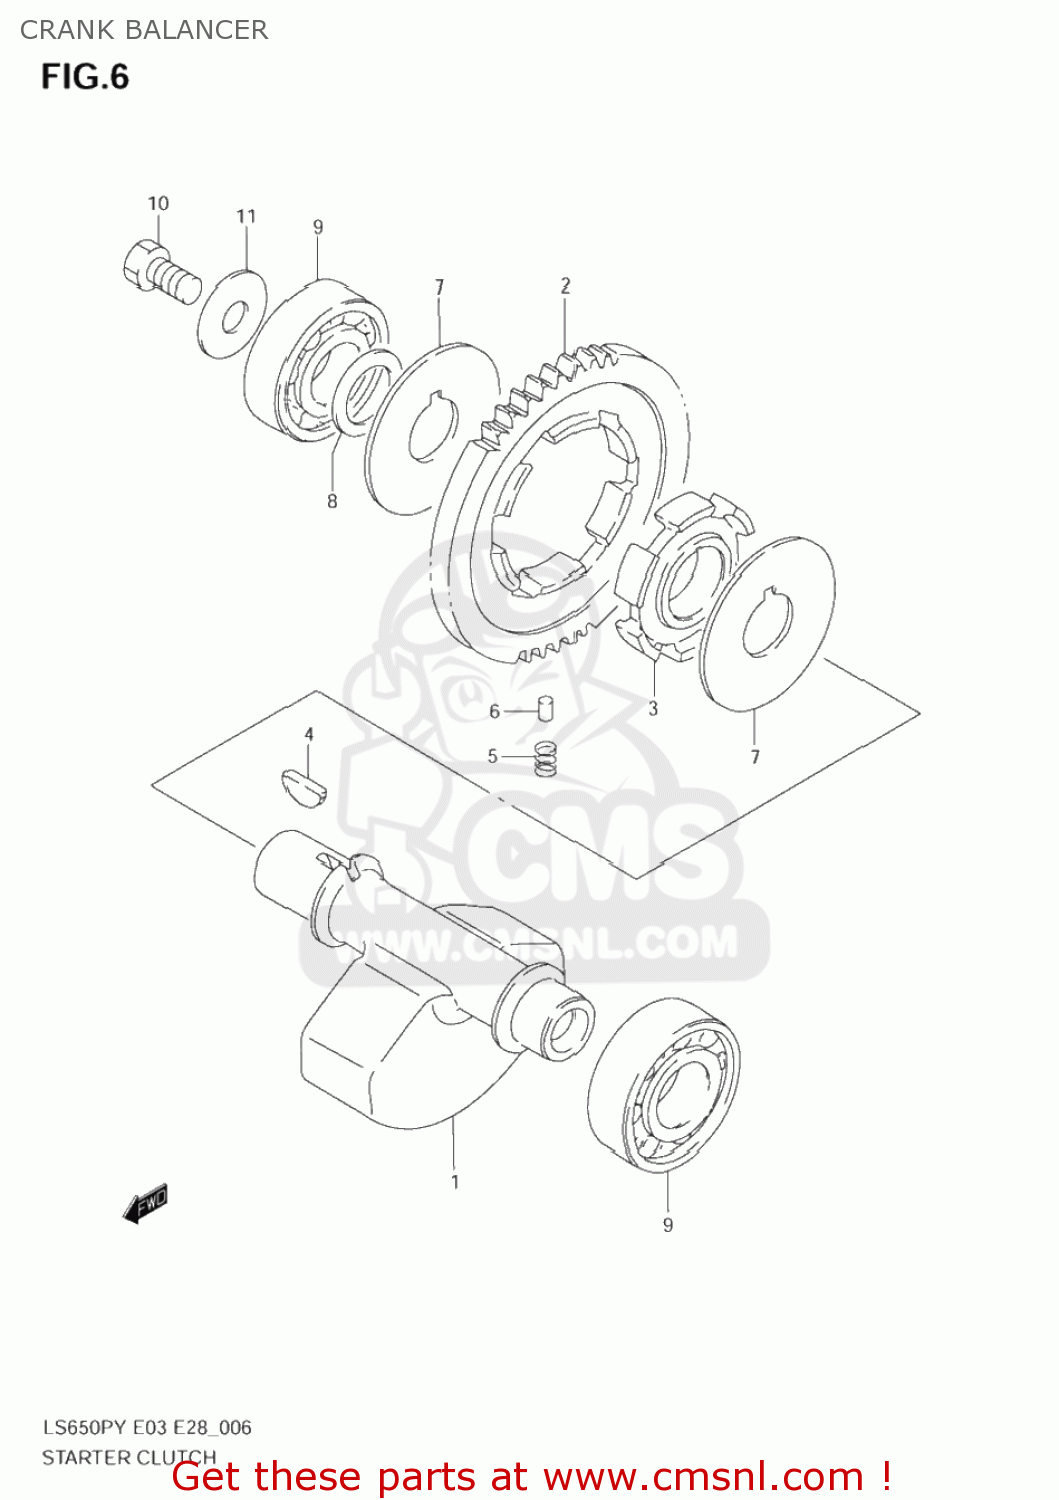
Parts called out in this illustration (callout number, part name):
1	SHAFT,CRANK BALANCER
2	GEAR,CRANK BALANCER DRIVEN
3	RACE,CRK BAL DRIVEN GEAR INNER
4	KEY
5	SPRING
6	PIN(4.5X9.5)
7	WASHER
8	THRUST WASHER
9	BEARING(20X47X14)
10	BOLT
11	WASHER
